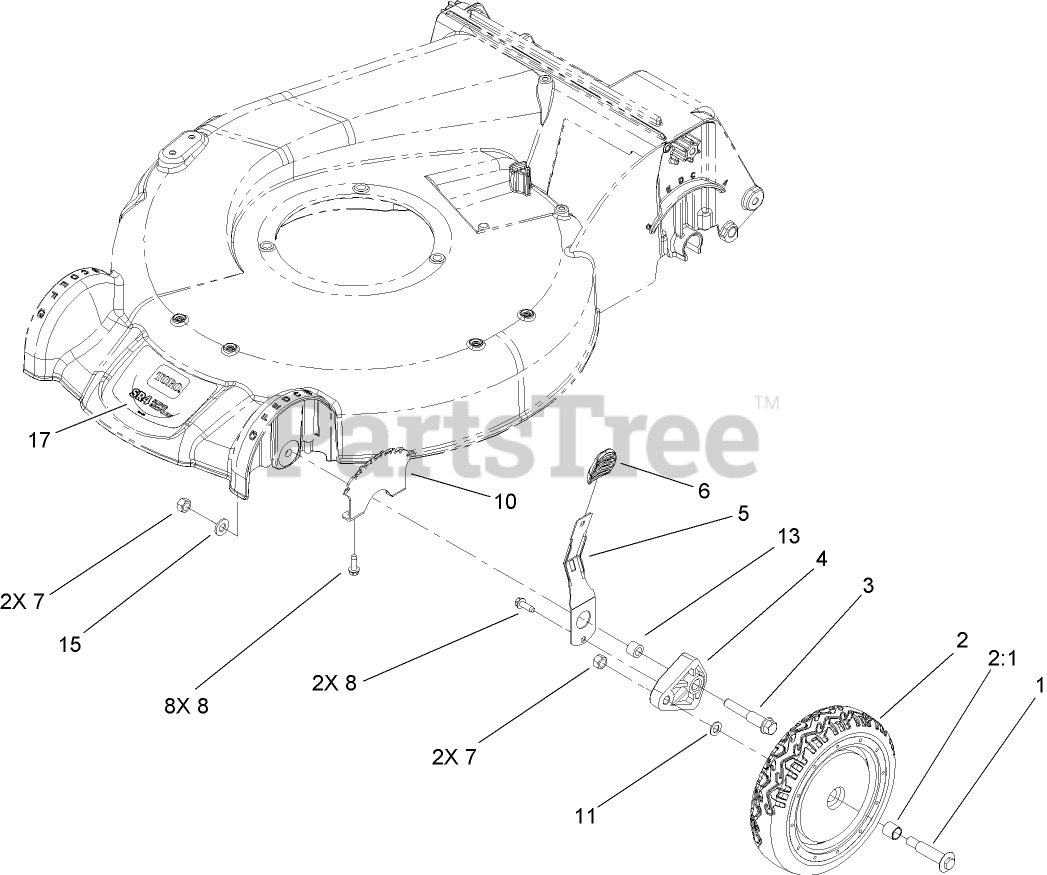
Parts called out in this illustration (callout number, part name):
1	BOLT-SHOULDER
2	WHEEL ASM
2:1	BUSHING
4	ARM-PIVOT
5	ARM-SPRING
6	KNOB-LEVER, HOC
7	LOCKNUT
8	SCREW-HWHTF
10	PLATE-HOC
11	WASHER
13	SPACER-WHEEL
15	WASHER-FLAT
17	DECAL-SUPERCARE
